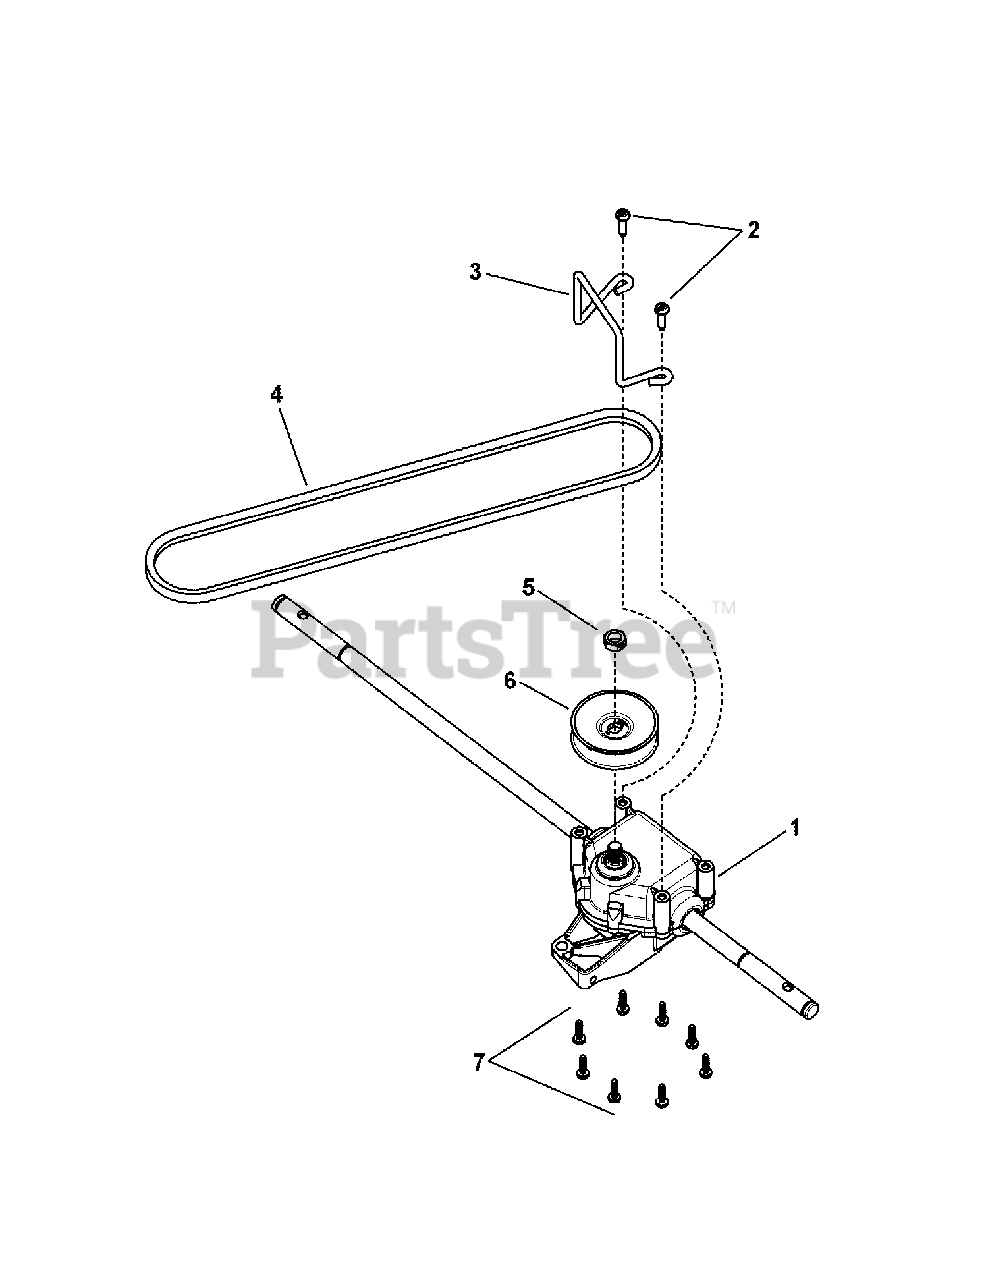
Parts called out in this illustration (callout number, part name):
1	TRANSMISSION, 21" WBM, RD, Snapper
2	SCREW, #10-16 x 3/4" Pan Head Self-Tap, Combo
3	BELT GUIDE, Transmission
4	BELT, Traction Drive, 21" Pivot Handle
5	NUT, 3/8-16 Hex Center Lock, GR5
6	PULLEY, Trans Var Speed, LC WBM
7	SCREW, 7mm x 1 x .550 AB Point
